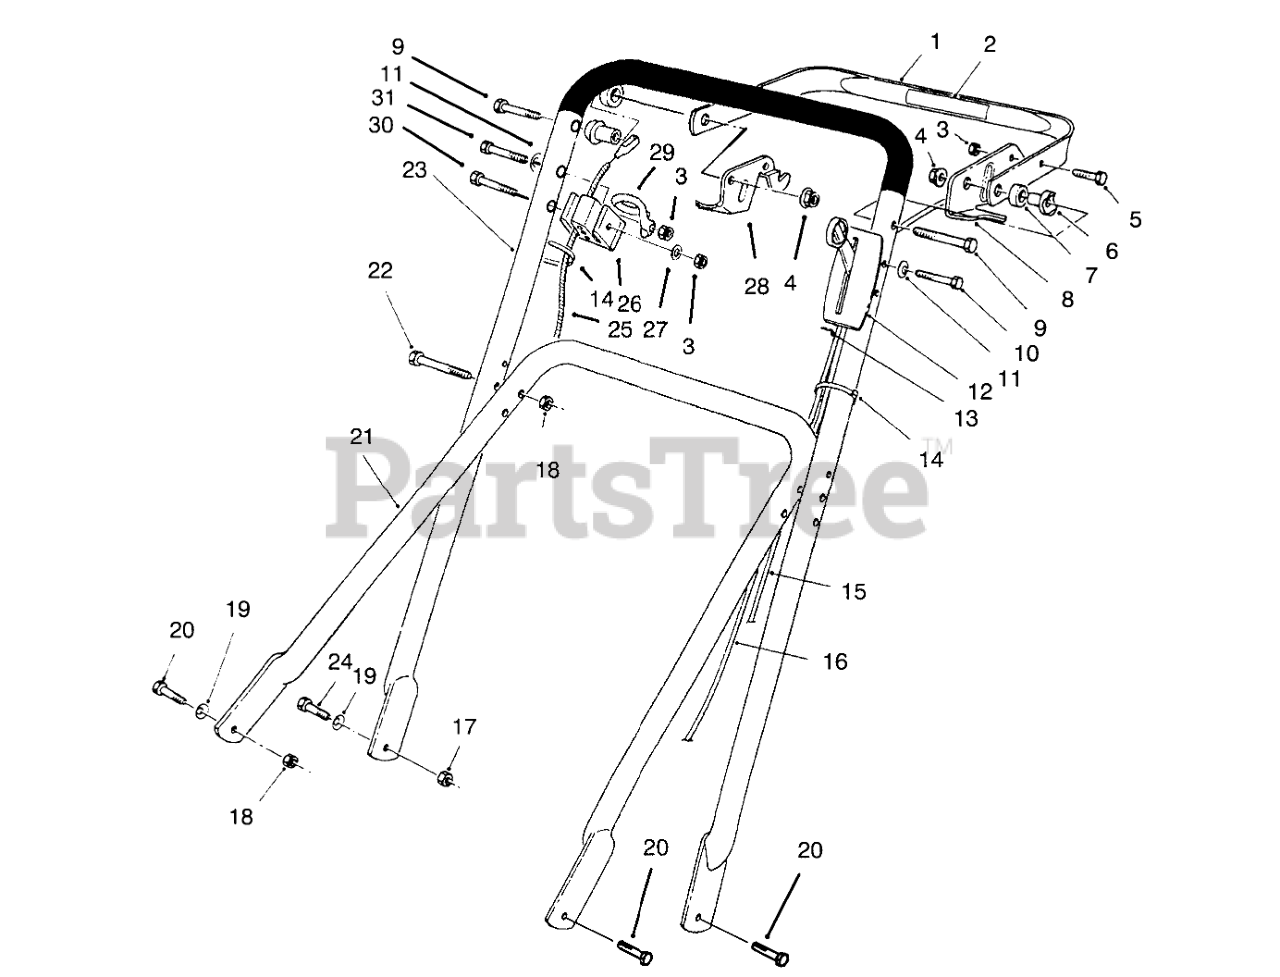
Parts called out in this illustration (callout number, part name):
1	Bar-Control
2	DECAL - TRACTION CONTROL
3	NUT-LOCK, NI
4	NUT-LOCK, NI
5	SCREW-HH
6	SPACER-SUPPORT
7	SPACER-NYLON
8	LEVER-CONTROL
9	SCREW-HH
10	SCREW-HH
11	WASHER
12	BRACKET-CONTROL, THROTTLE
13	E-RING
14	TIE-CABLE
15	CABLE-TRACTION
16	CABLE-THROTTLE
17	NUT-LOCK, NI
18	NUT-LOCK, NI
19	WASHER-BELLEVILLE
20	SCREW-HH
21	Handle-Lower
22	SCREW-HH
23	Handle
24	SCREW-HH
25	CABLE - BRAKE
26	SUPPORT-CABLE
27	WASHER-FLAT
28	LEVER-CONTROL
29	GUIDE-ROPE
30	SCREW-HH
31	SCREW-HH
